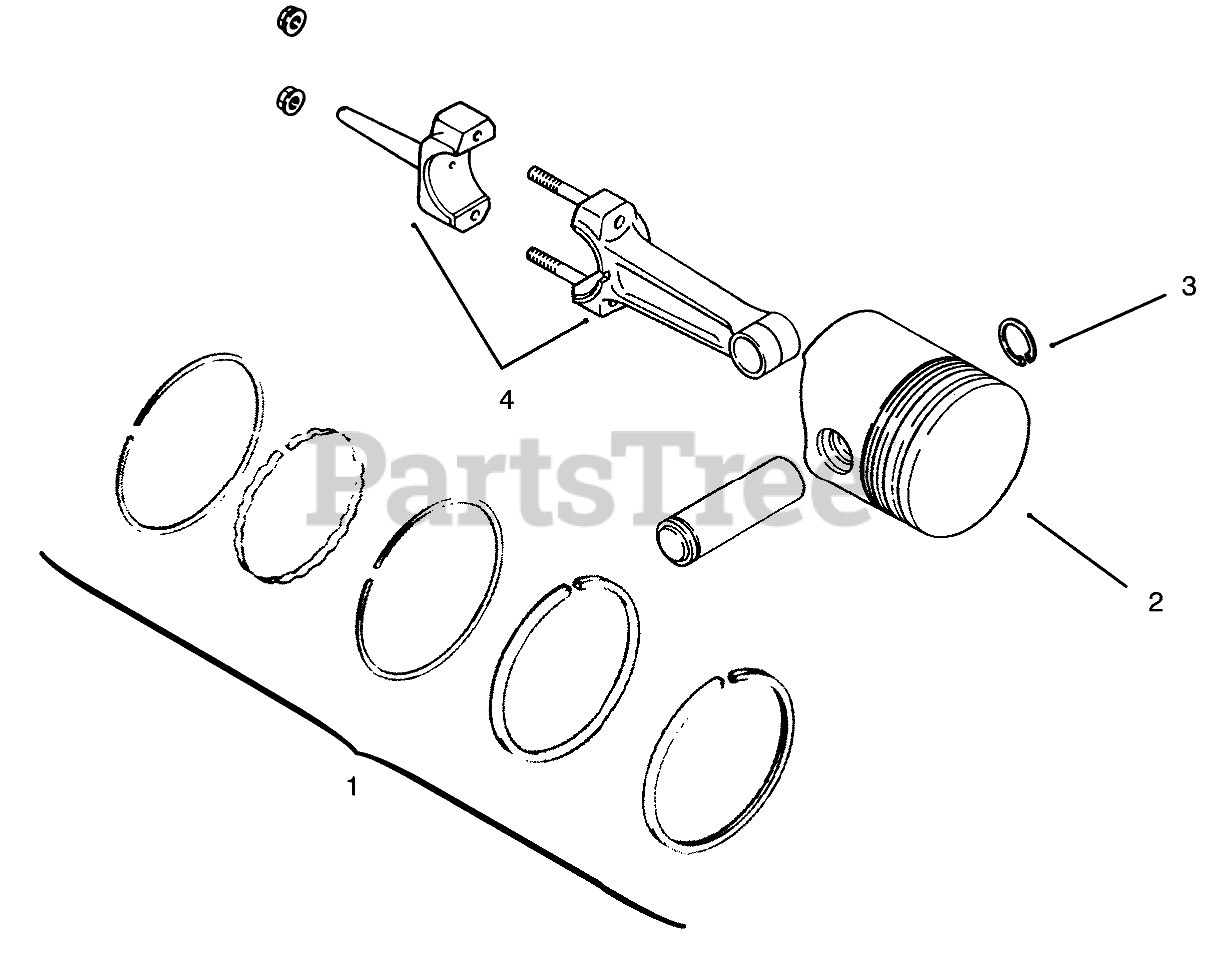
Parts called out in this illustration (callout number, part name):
1	Set-Ring, Std. &.003
2	Piston w/Ring Set Std.
3	Piston Pin Retainer
4	Rod-Connecting Std.
